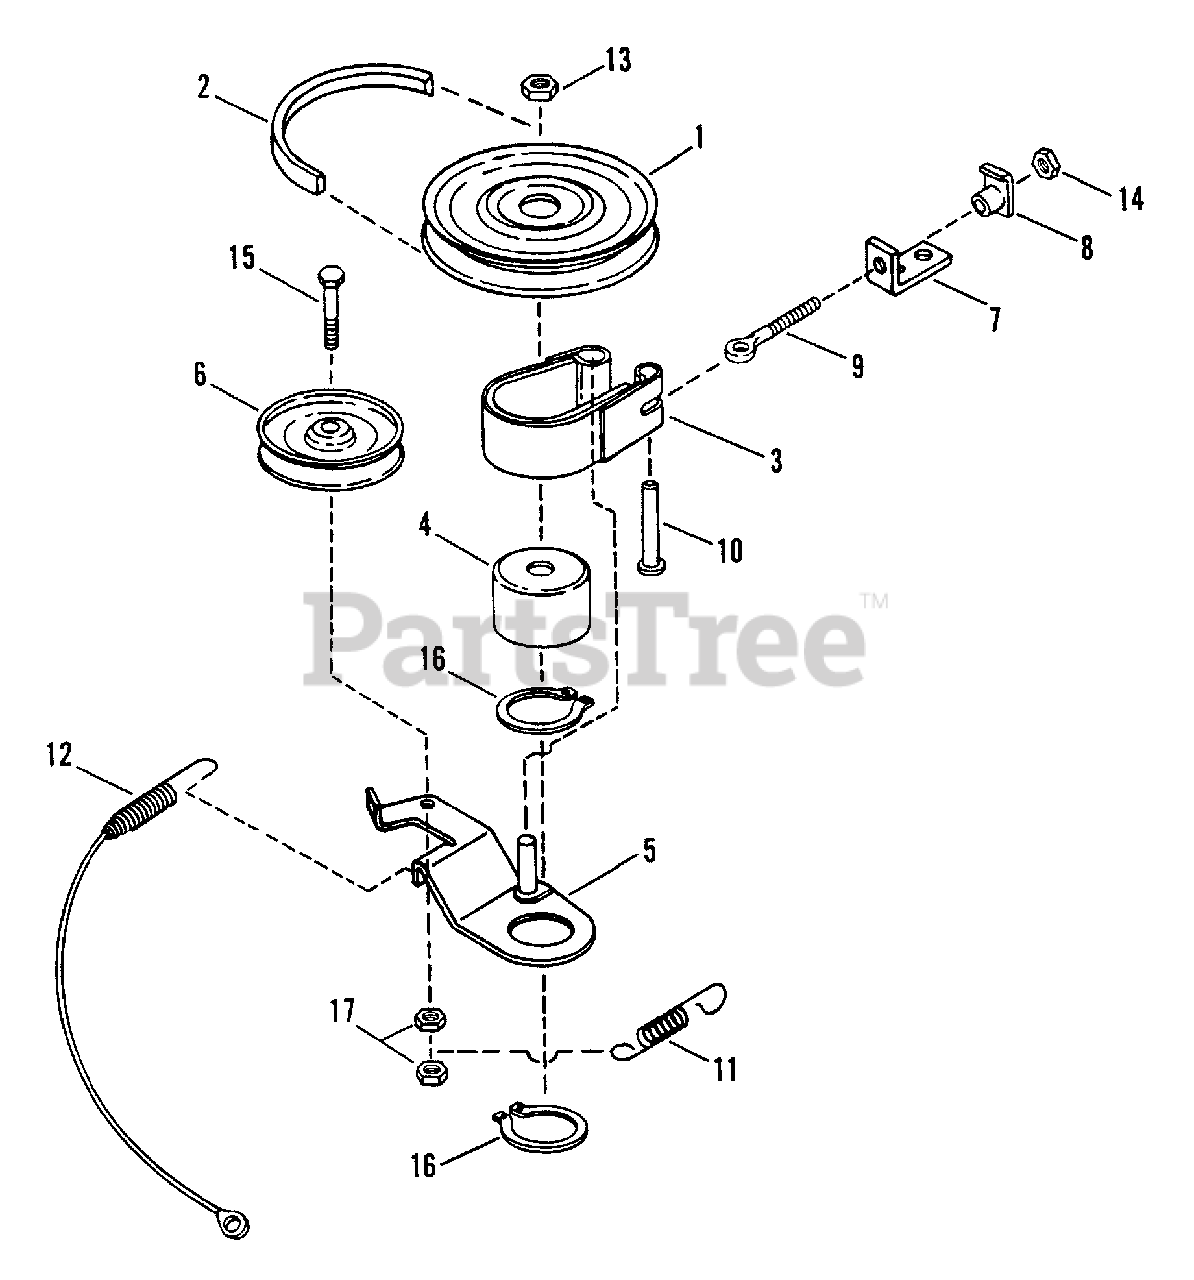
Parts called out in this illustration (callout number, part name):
1	PULLEY, Drive
2	BELT, Drive
3	BAND, Brake Assembly
4	DRUM, Brake A101
5	ASSEMBLY, Brake Arm
6	PULLEY, Idler
7	ANCHOR, Brake
8	TEE-NUT, 1/4-20
9	BOLT, 1/4-20 Eye
10	PIN, Clevis, 1/4 x 1 1/4"
11	SPRING, Blade Brake
12	CABLE, Blade 28.5"
13	NUT, 3/4-16 Hex Jam
14	NUT, 1/4-20 Hex
15	SCREW, 3/8-24 x 2" Hex Hd. Cap
16	RING, 2" External Retaining
17	NUT, 3/8-24 Hex Lock
